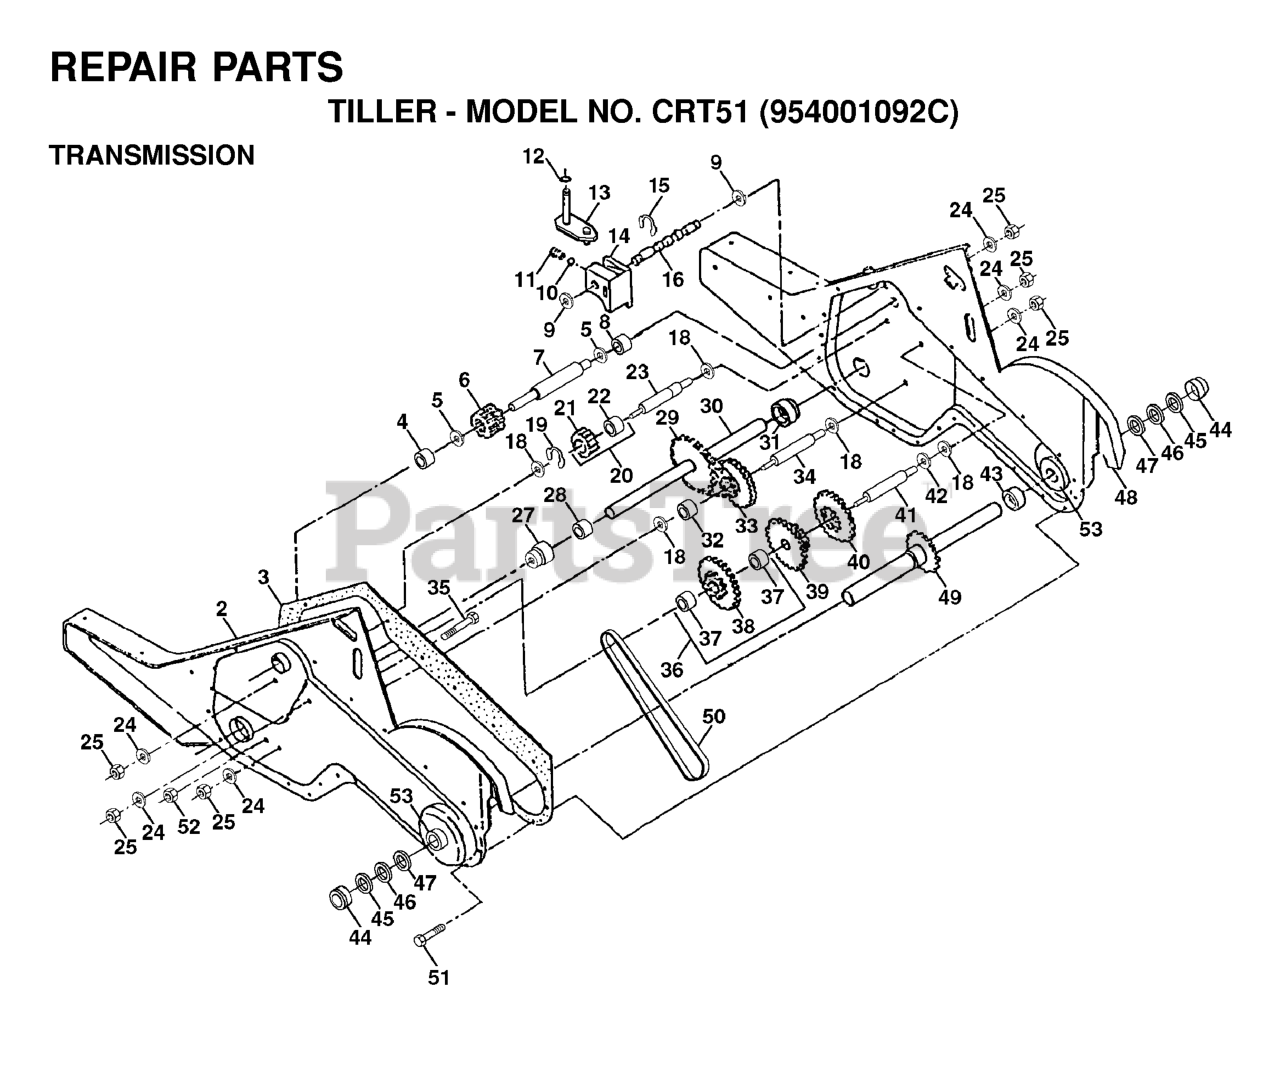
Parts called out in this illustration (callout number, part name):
1	TRANSMISSION ASSEMBLY
2	GEARCASE LH W/BRG
3	GASKET TI
4	NEEDLE BRNG LT
5	THRUST WASHER
6	GEAR.PINION.INPUT
7	SHAFT.INPUT."D".TILLER
8	BEARING TI
9	WASHER SEAL CRT
10	STEEL BALL KIT
11	SPRING-SHIFT CRT
13	BRACKET ASM.SHIFT.CRT
14	SHIFT FORK TI
16	SHIFT SHAFT
20	GEAR ASSY CRT
21	GEAR-REV IDLR CRT
22	NEEDLE BEARING TI
24	LOCKWASHER
25	NUT.ASF.HEX.7/16
27	BEARING, SHAFT LH CRT
30	GROUND SHAFT ASS'Y
31	BEARING, SHAFT RH CRT
33	SPRCKT 8 GEAR CRT
34	SHAFT.SECONDARY.REDUCTION.CRT
35	SCRW WHIZ LOK CRT
36	SPROCKET ASSY W/ BRG
37	BEARING
38	SPROCKET TINE
41	SHAFT.REDUCTION.TILLER
42	BRNG RACE T
44	CUP
45	RING.SPIRAL.CRT.TILLER
47	OIL SEAL STD
48	GEARCASE RH W/BRG
49	TINE SHAFT
50	CHAIN.TILLER
51	SCREW
53	BEARING KIT
